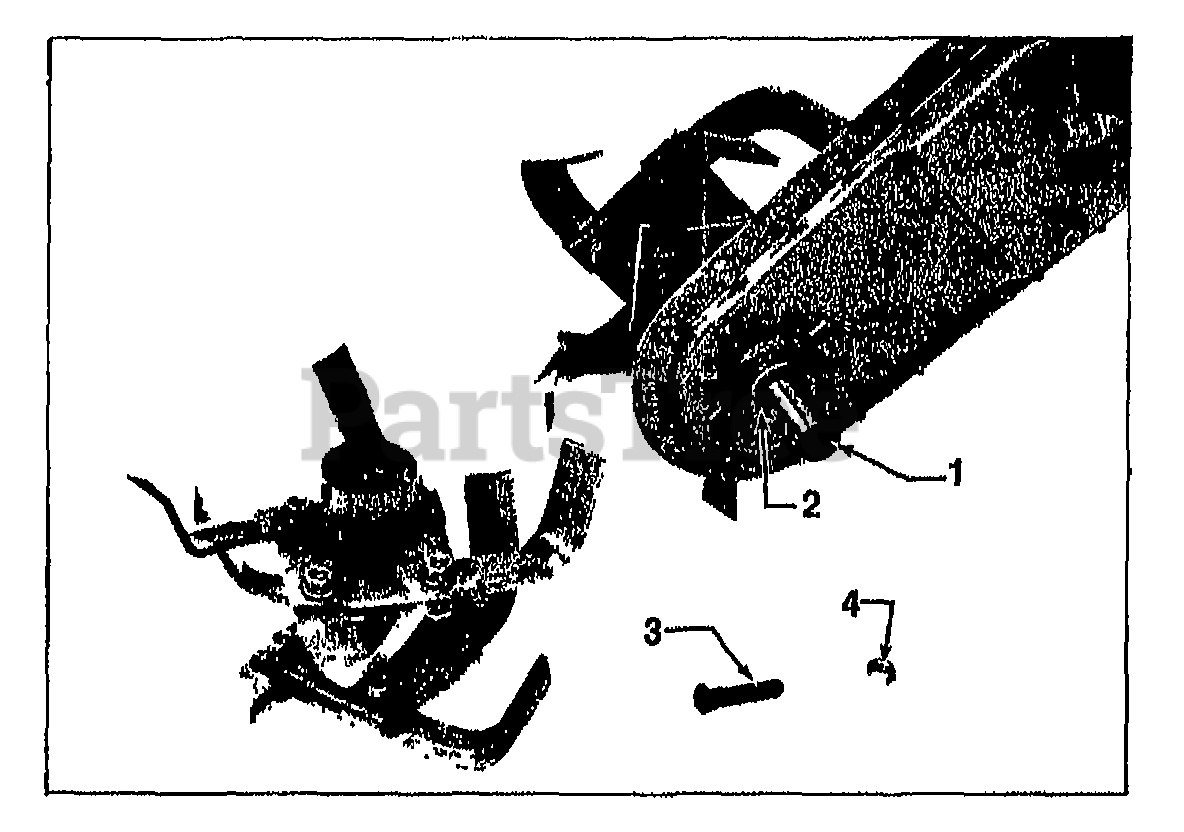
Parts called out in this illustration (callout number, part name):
1	TINE SHAFT-WELD
2	SEAL-OIL
3	BOLT-HH 3/8-16X1.75 G8 ZP (ATTACHES TINE HOLDERS TO TINE SHAFT)
4	NUT-H/LK 3/8-16
